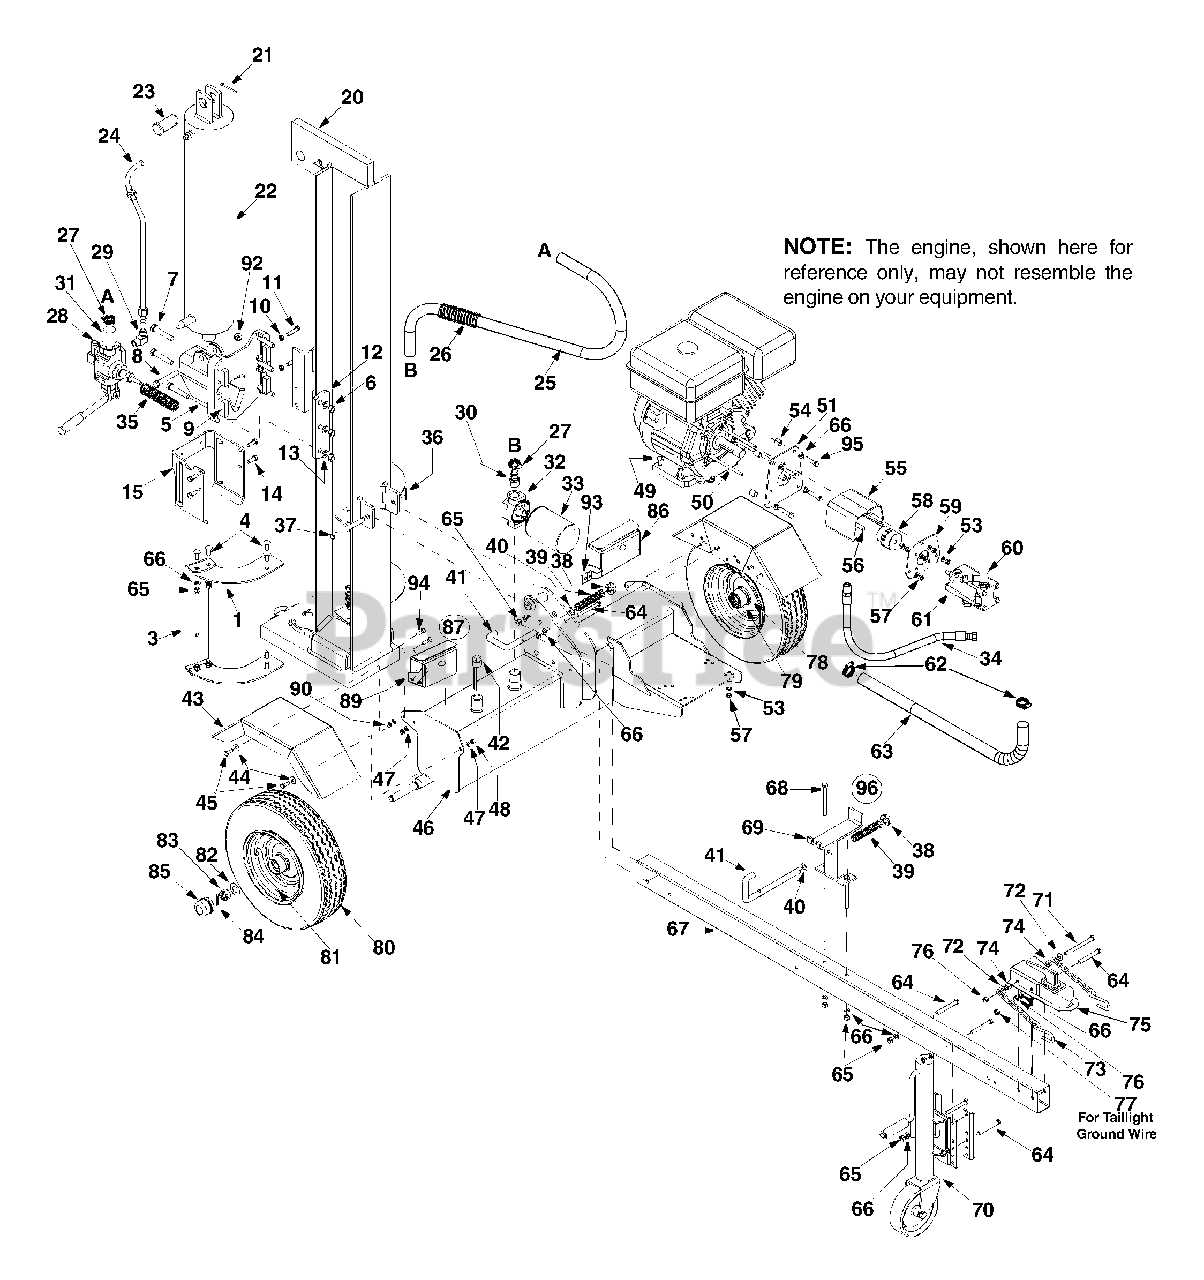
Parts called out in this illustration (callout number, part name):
4	Carriage Bolt 3/8-16 x 1.0
5	Wedge Assembly
6	Lock Nut 1/2-20
7	Hex Cap Screw 1/2-20 x 2.75
8	Hex Screw 1/2-13 x 3.25
9	Adjustable Gib
10	Hex Jam Nut 3/8-24
11	Hex Cap Screw 3/8-24 x 1.5
13	Lock Washer 1/2
14	Hex Screw 3/8-16 x 1.0
20	Beam Assembly
21	Cotter Pin
23	Clevis Pin
24	Hydraulic Tube
25	Return Hose 3/4" ID x 44" Lg.
26	Hose Guard
27	Hose Clamp 5/8"
28	Return Elbow
29	90 Degree Solid Male Adapter
30	3/4" Hose Adapter
32	Filter Housing
33	Oil Filter
34	High Pressure Hydraulic Hose
35	Hose Guard
36	Cotter Pin 1/8"
37	Hinge Pin 1/2 x 4.8" Lg.
39	Compression Spring 4"
40	Flat Washer.635 ID x.93 OD
41	Locking Rod
42	Vented Dipstick
44	Lock Washer 5/16
45	Hex Screw
46	Frame Assembly 7.0 Gal
47	Lock Washer 5/16
48	Hex Nut 5/16-18
49	Hex Cap Screw 5/16-24 x 1.75
50	Hex Cap Screw 5/16-24 x 5.25
54	Spacer.385 x.623 x.750 Lg.
55	Coupling Shield
56	Key
57	Hex Nut 5/16-24
58	Flex Coupling, 1.0 x .4375 "Stamped L090"
58	Coupling Half, 1.00
58	Coupling Half, .500
58	Spider Bushing
60	Adapter 7/8-14
61	Pump (16 gmp)
61	Pump (15 gmp) Service Kit
61	Pump (15 gmp)
62	Hose Clamp
63	Suction Hose
64	Hex Cap Screw 3/8-16 x 3.0
65	Hex Nut 3/8-16
66	Lock Washer 3/8
68	Hex Cap Screw 3/8-16 x 4.0
70	Adjustable Jack Stand
71	Hex Cap Screw 3/8-16 x 4.25
72	Flat Washer.385 ID x.870 OD
73	Chain
75	Hitch Coupler
76	Lock Nut 3/8-16
77	Hex Jam Nut 3/8-16
78	Bearing Seal
79	Bearing Cone
80	Wheel Assembly
82	Flat Washer .76" ID x 1.5" OD
83	Slotted Nut 3/4-16
84	Cotter Pin 5/32" x 1-1/4" Lg.
92	Lock Nut 1/2-13
93	Tinn Clip Nut 1/4-20
94	Hex Screw 5/16-24
95	Hex Screw 3/8-16 x 1.75
